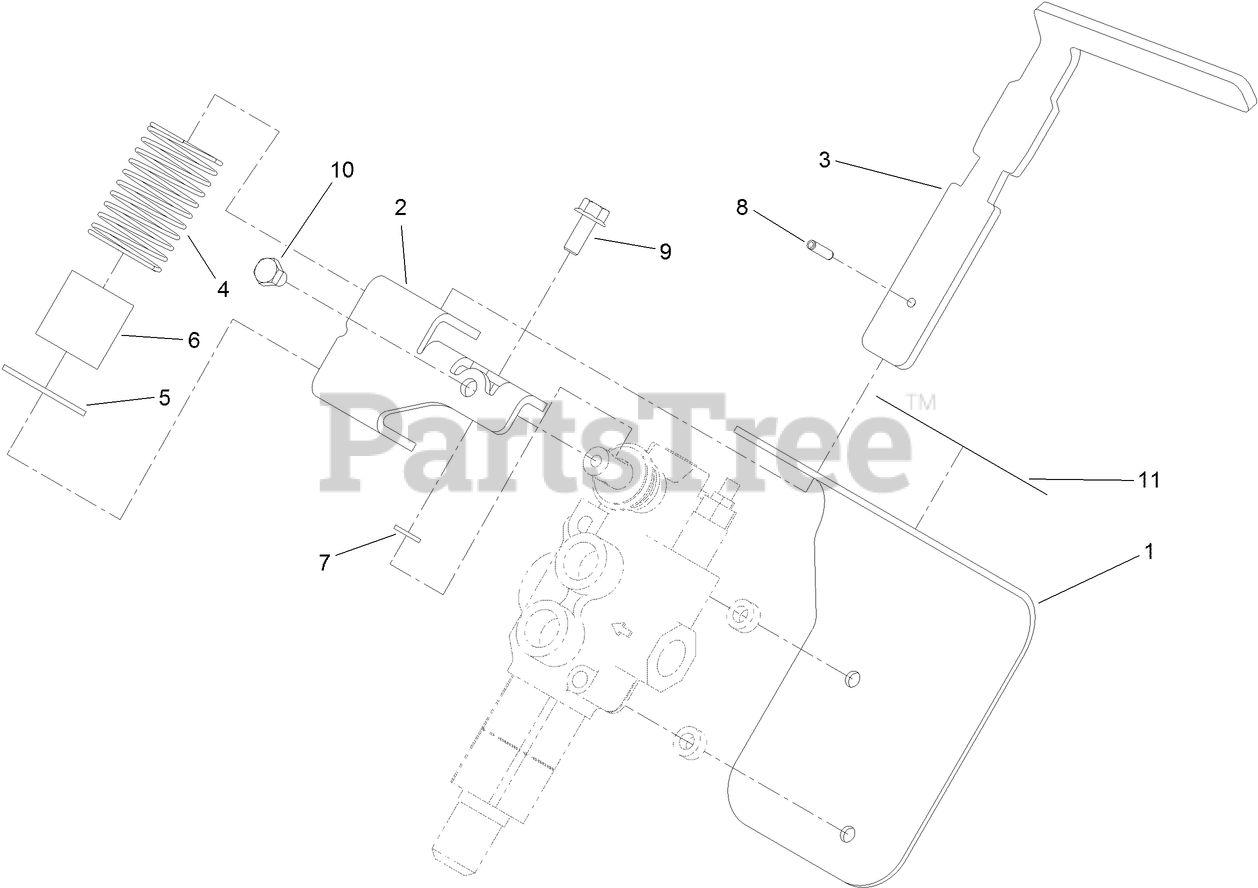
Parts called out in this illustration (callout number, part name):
1	BRACKET-AUXILIARY
2	MOUNT-LEVER, AUXILIARY
3	HANDLE-LEVER, AUXILIARY
4	SPRING
5	RETAINER-SPRING, AUXILIARY
6	TUBE-SPRING
7	WASHER-LOCK
8	PIN-SPRING
9	SCREW-HHF
10	SCREW-HH
11	DECAL-AUXILIARY, CE
